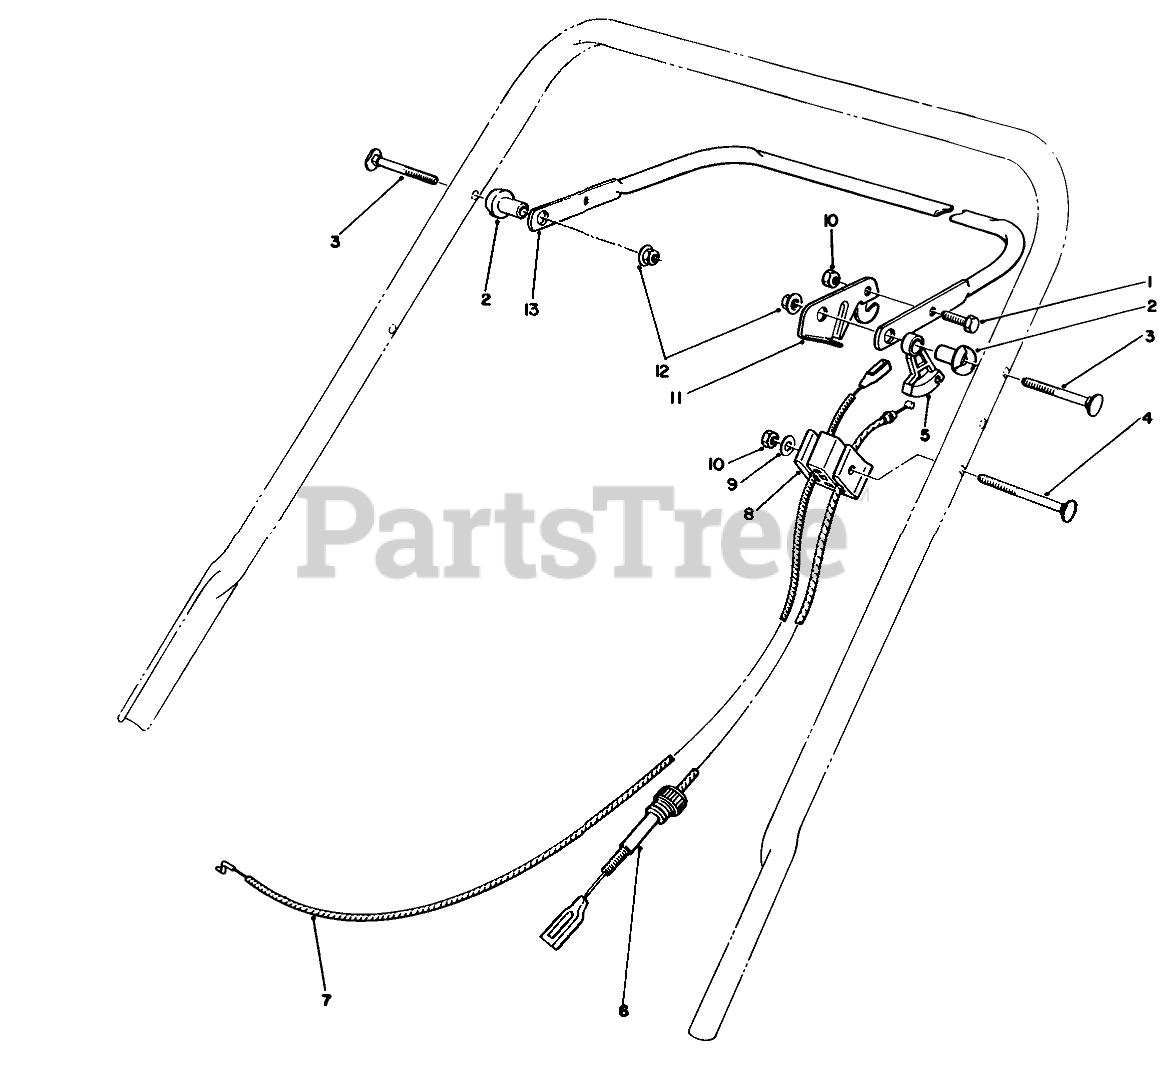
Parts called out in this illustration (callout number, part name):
1	SCREW-HH
2	SPACER-SUPPORT
3	5/16-18 X 2 HNDLE SCREW
4	HANDLE SCREW
5	LEVER-TRACTION
6	CABLE-TRACTION
7	BRAKE CONTROL
8	SUPPORT-CABLE
9	WASHER-FLAT
10	NUT-LOCK, NI
11	LEVER-CONTROL
12	NUT-LOCK, NI
13	Bar-Control
